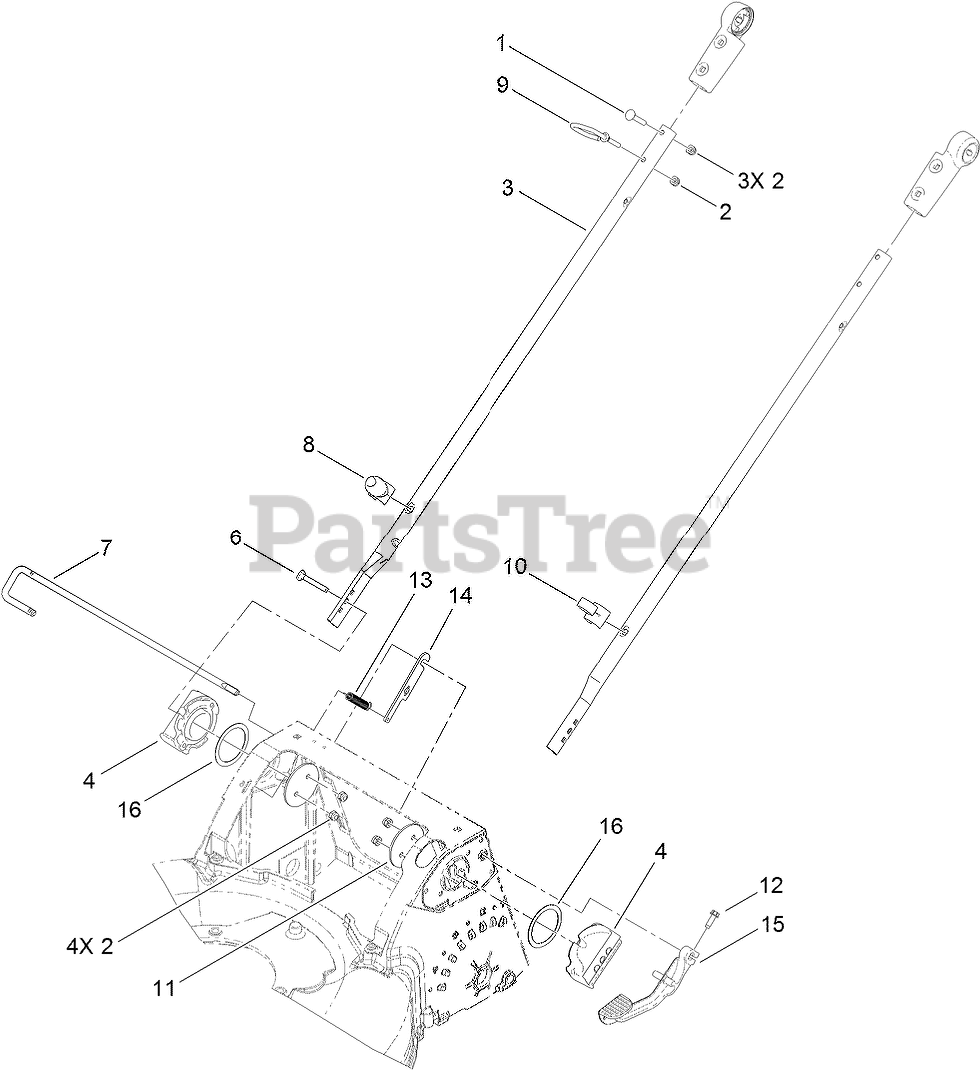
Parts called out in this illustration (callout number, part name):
1	SCREW-CARR
2	NUT-LOCK, NI
3	TUBE-LOWER
4	MOUNT-HANDLE
6	SCREW
7	ROD-RELEASE, HANDLE
8	GUIDE-ROPE, LOWER
9	GUIDE-ROPE, UPPER
10	GUIDE-CABLE
12	SCREW-HWHTF
13	SPRING-EXTENSION
14	PLATE-ROD, RELEASE
15	LEVER-RELEASE
16	WASHER-NYLON
